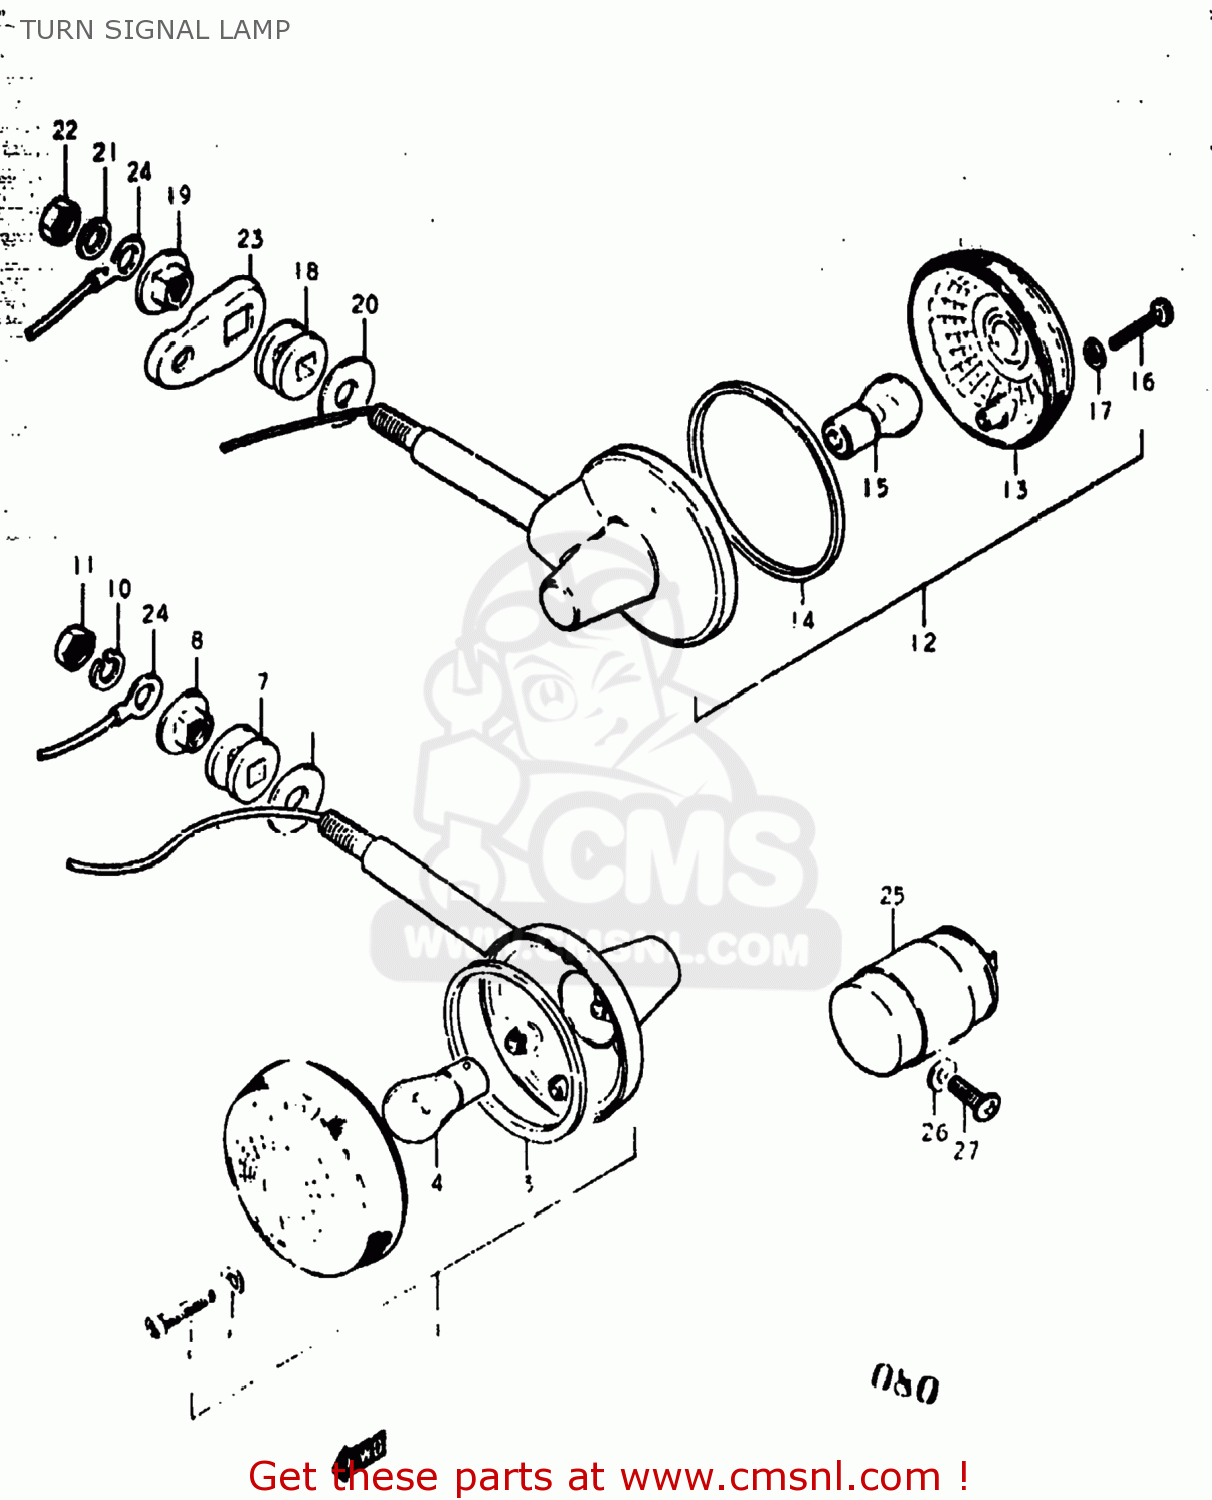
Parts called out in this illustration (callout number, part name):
1	LAMP ASSEMBLY,FRONT TURN SIGNAL
2	LENS
3	GASKET (NAS)
4	BULB(12V23W,STANLEY,A4577A)
5	SCREW
6	GASKET (NAS)
7	CUSHION
8	SPACER,RR TURNSIGNAL LAMP
9	WASHER
10	LOCK WASHER
11	NUT
12	LAMP ASSEMBLY,REAR TURN SIGNAL
13	LENS
14	GASKET (NAS)
15	BULB(12V23W,STANLEY,A4577A)
16	SCREW
17	GASKET (NAS)
18	CUSHION
19	SPACER,RR TURNSIGNAL LAMP
20	WASHER
21	LOCK WASHER
22	NUT
23	BRACKET,TURN SIGNAL
24	WIRE
25	RELAY,TURN SIGNAL
26	WASHER
27	SCREW
